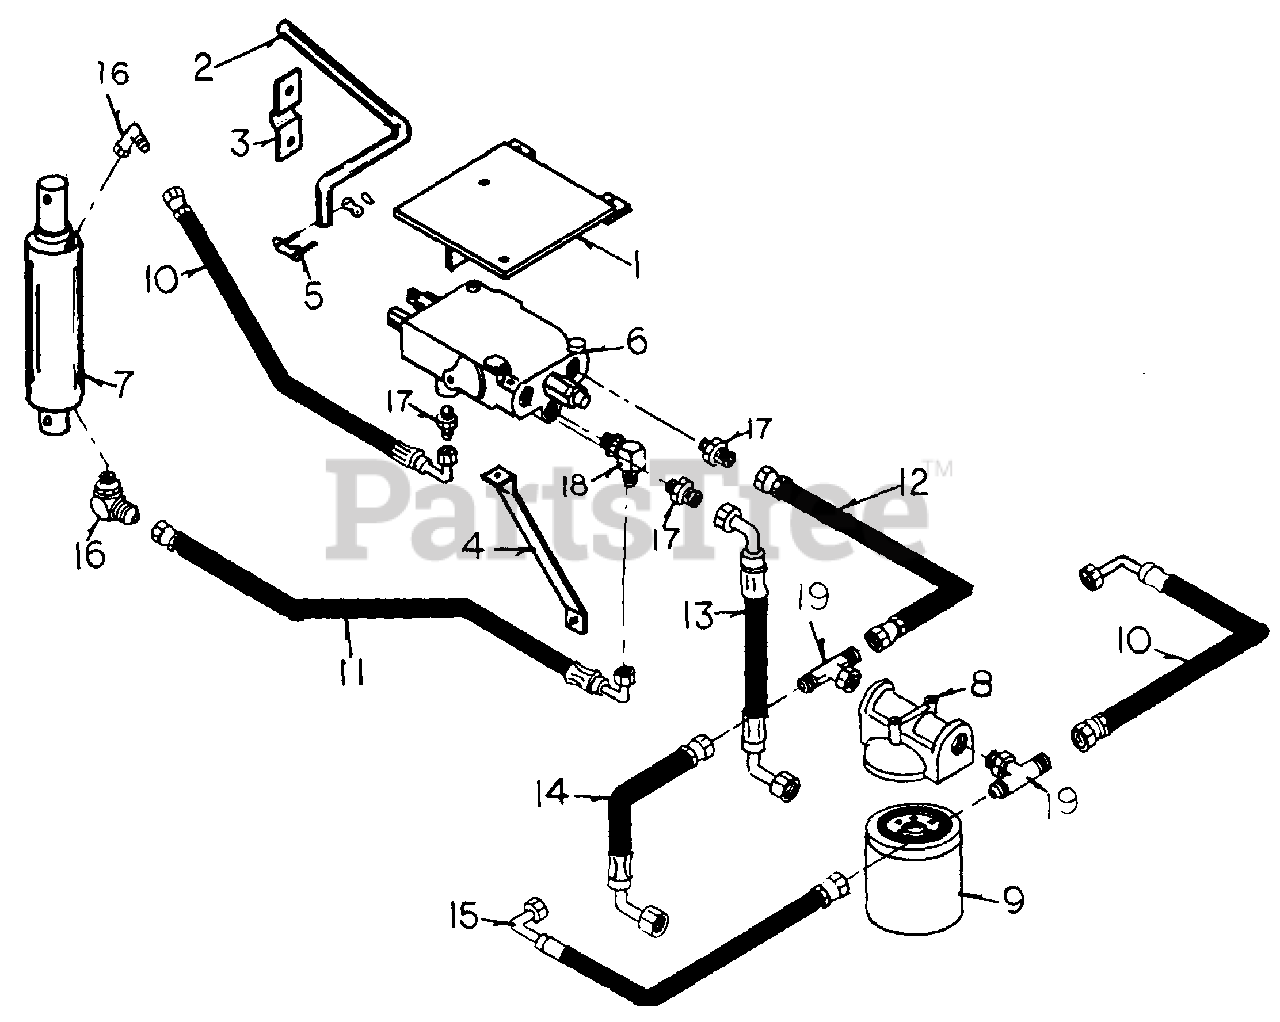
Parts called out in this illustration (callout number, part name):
1	Valve Mount
3	Bearing, Clutch Brake Cross Rod
4	Valve Support
5	Connecting Link, #50
8	Housing, Oil Filter
9	Element, Oil Filter
10	Hose, 3/8" ID x 26" Long
11	Hose, 3/8" ID x 31" Long
12	Hose, 3/8" ID x 20" Long
13	Hose, 3/8" ID x 13" Long
14	Hose, 3/8" ID x 11.5" Long
15	Hose, 3/8" ID x 21" Long
16	Male O-ring, 90° Male Tube Adp.
17	Male O-ring, Male Tube Adp.
18	Male O-ring, 90° Male Tube Adp.
19	Male Tube, Male O-ring Tee
